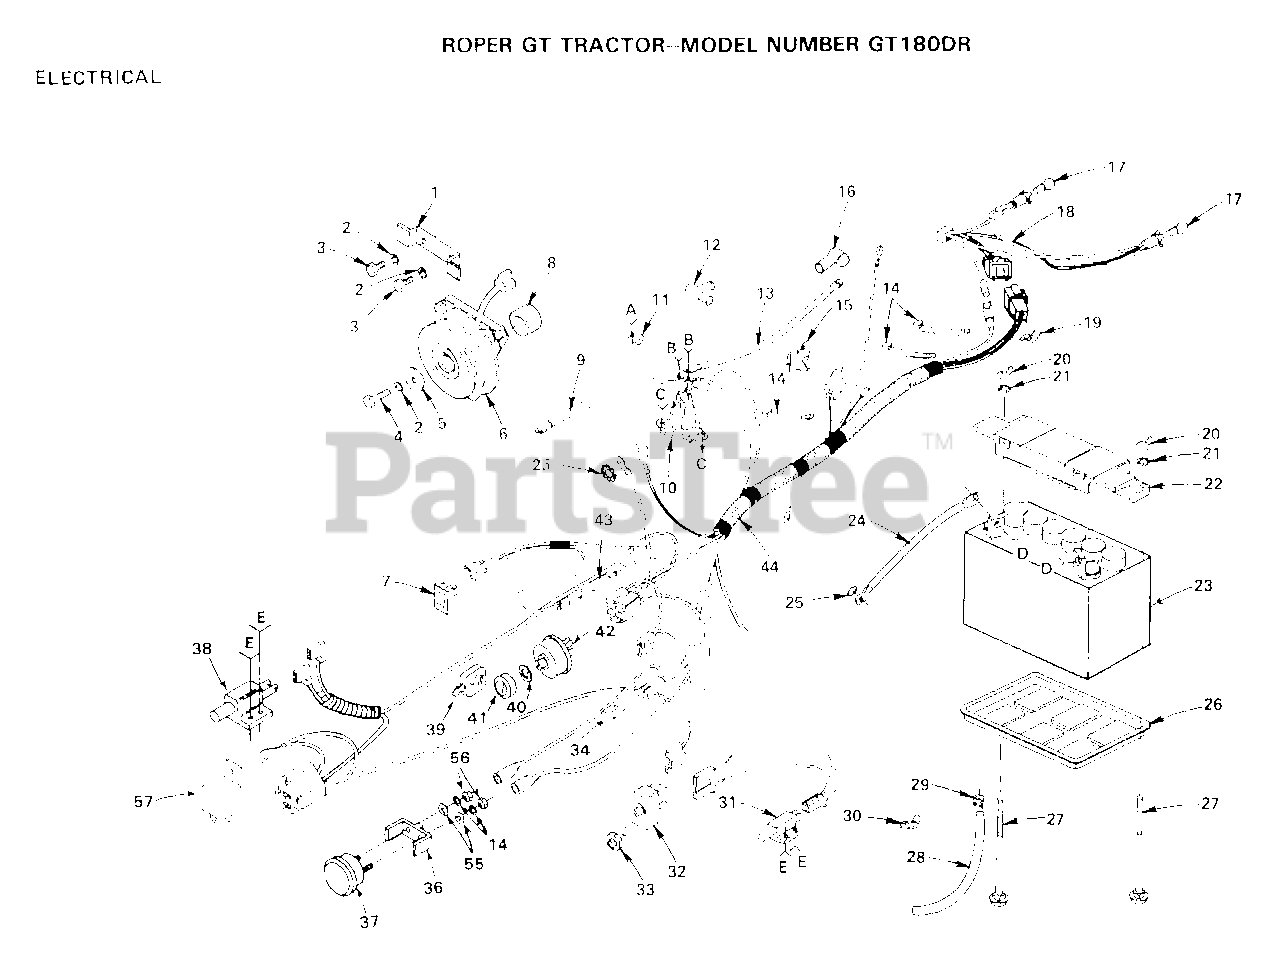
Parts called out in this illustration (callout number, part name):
1	STOP CLUTCH T
2	LOCKWASHER
3	BOLT
4	BOLT
5	WASHER GT
6	CLUTCH.ELECTRIC.T
8	SPACER-CLUTCH GT
9	CABLE-BATTERY T
12	TERM COVER DUAL
15	CLIP-HARNESS
18	HARNESS T
19	CLIP GT
21	LOCKWASHER GT
24	CABLE T
25	LOCKWASHER
26	"TRAY T, BATTERY"
27	BOLT
28	No Desciption for Part
29	HOSE CLAMP T
30	CLIP GTV
31	SWITCH-INTER. GT
32	SWITCH.PTO.T
33	HEX NUT T
34	FUSE-30 AMP
37	AMMETER T
38	SWITCH T
55	WASHER
57	RELAY ASSY T
